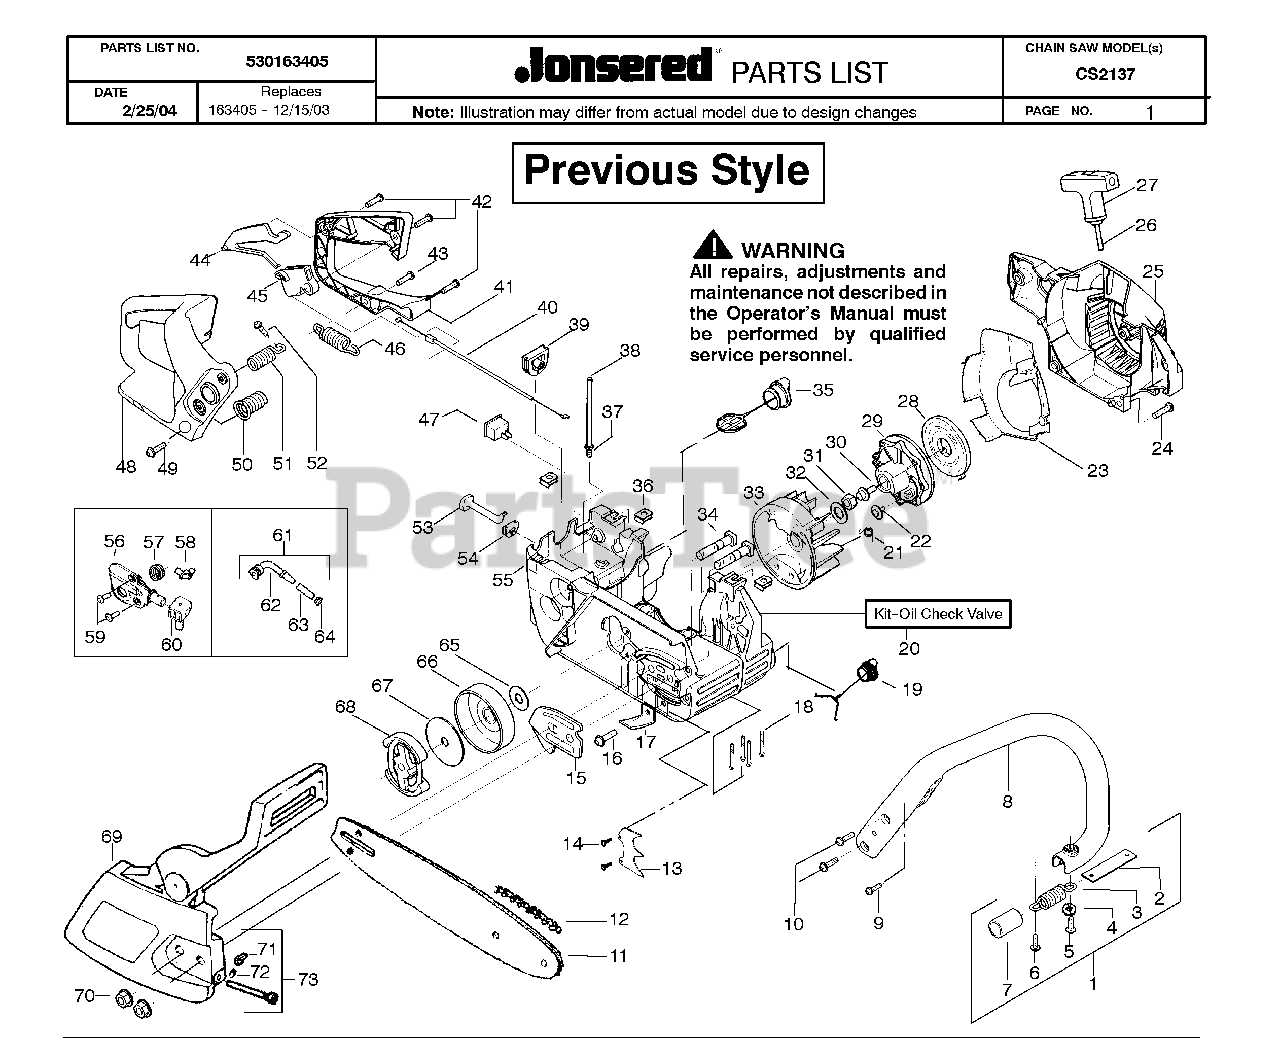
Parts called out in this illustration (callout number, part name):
1	ASSY-ISOLATOR
2	STRAP
3	SPRING
8	HANDLE
13	SPIKE 36/41
14	SCREW-10-16 X 1/2, TYPE 2
17	CHAIN CATCHER 36/41
19	OIL TANK CAP
20	KIT-OIL CHECK VALVE
21	SPRING STR DOG
23	AIR BAFFLE
24	SCREW,STRTR CVR 36/41
27	HANDLE STARTER
29	STARTER PULLEY
31	NUT-FLYWHEEL
32	WASHER-FLYWHEEL
33	FLYWHEEL ASS'Y
35	TANK CAP
37	FUEL LINE FITTING
40	THROTTLE WIRE
42	SCREW,FRONT HBAR 36/41
43	SCREW-10-14 X 13/16 (PL
44	THROTTLE LOCK
45	THROTTLE TRIGGER
46	SPRING
50	SPRING
51	SPRING
57	WORM GEAR
62	PICK-UP OILER
63	FILTER
64	PLUG
65	DUST COVER 36/41
66	CLUTCH DRUM ASSY
67	FRICTION DISC,CLUTCH 36/41
68	CLUTCH ASSEMBLY
71	ADJUST PIN,BAR 36/41
